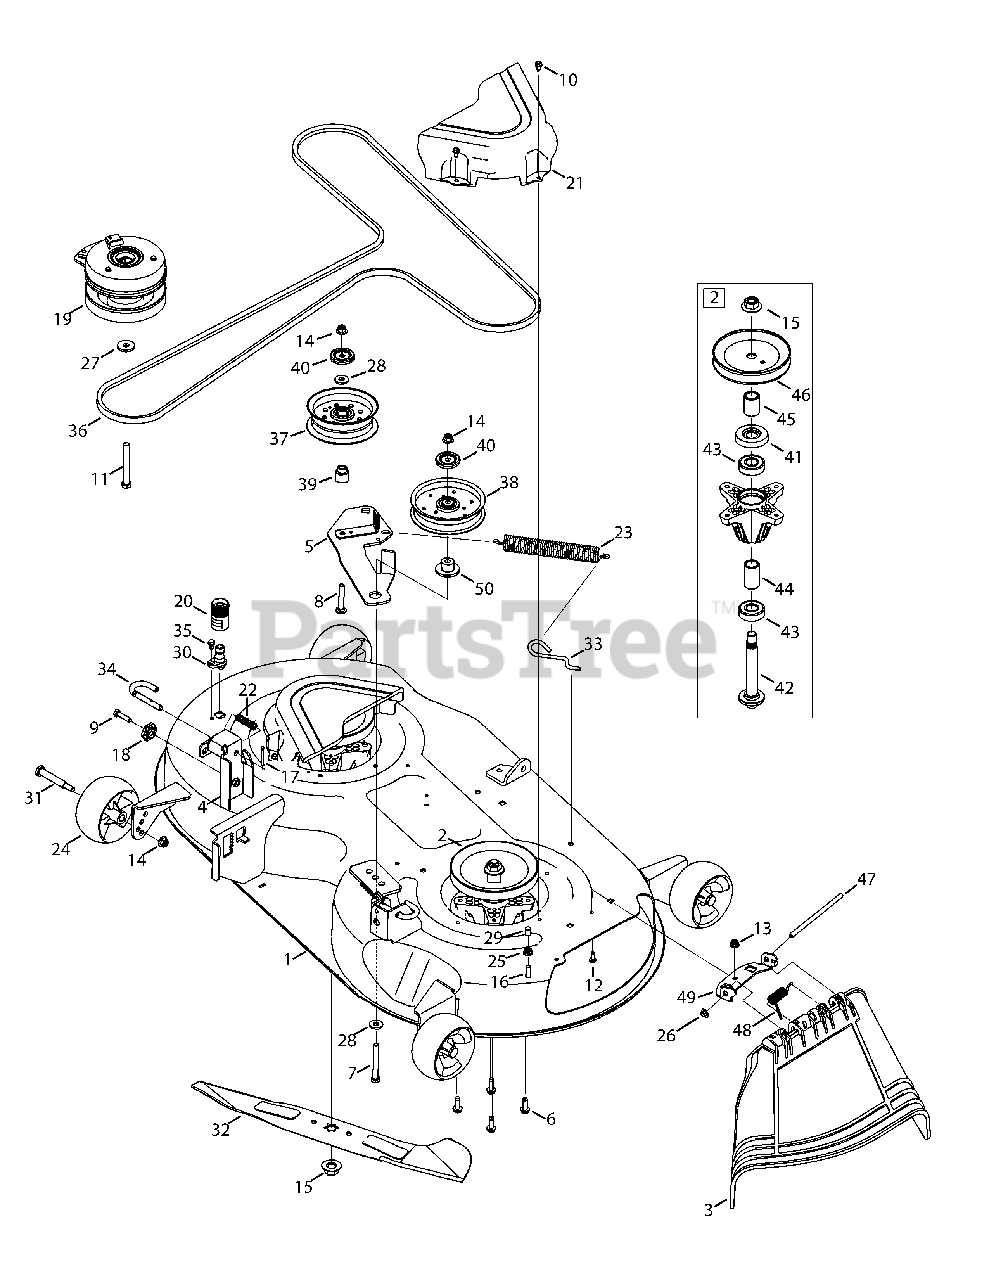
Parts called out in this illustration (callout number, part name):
1	46" Deck
2	Spindle Assembly
3	Chute Deflector Assembly
4	Deck Lift Bracket
5	Deck Idler Assembly
6	Hex Washer Screw, 5/16-18 x .750
7	Hex Cap Screw, 3/8-16 x 3.50
9	Hex Flange Screw, 3/8-16
10	Hex Washer Screw, 1/4-20 x .625
11	Screw, 7/16-20 x 3.25
12	Hex Cap Screw, 1/4-20 x .62
13	Nut, Flange Lock, 1/4-20, Nylon
14	Flange Lock Nut, 3/8-16
15	Hex Flange Nut, 5/8-18
16	Hex Cap Screw, 5/16-18 x 1.00
17	Cotter Pin, 5/32 x 1.25
18	Deck Adjustment Gear
19	Electric PTO Clutch
20	Water Nozzle Adapter
21	Belt Cover
22	Compression Spring, .66 x 1.9
23	Extension Spring, 1.25 OD x 1.751
24	Deck Ball Wheel, 5.0
25	Flange Lock Nut, 5/16-18
26	Push Cap
27	Flat Washer, .450 x 1.25 x .164
28	Flat Washer, .406 x 1.00 x .105
29	Cap, .290 x .500
30	Deck Wash Nozzle
31	Shoulder Screw, .5 x 2.5 x 3/8-16
32	Blade, 2 in 1, 23.25
33	Deck Spring Rod
34	Deck Hanger Rod
35	Shoulder Screw, 1/4-20 x 0.50
36	V-Belt
37	Pulley, Idler, 4.50" Dia.
38	Idler Pulley, 5.00 Dia.
39	Shoulder Spacer
40	Pulley Cap
41	Bearing Shield
42	Spindle Shaft
43	Ball Bearing
44	Spacer, .792 x 1.060 x 1.860
45	Spacer, .8 x 1.1 x 2.26
46	Deck Pulley
47	Hinge Pin
48	Spring, Torsion, .440 ID x 1.75
50	Shoulder Spacer
